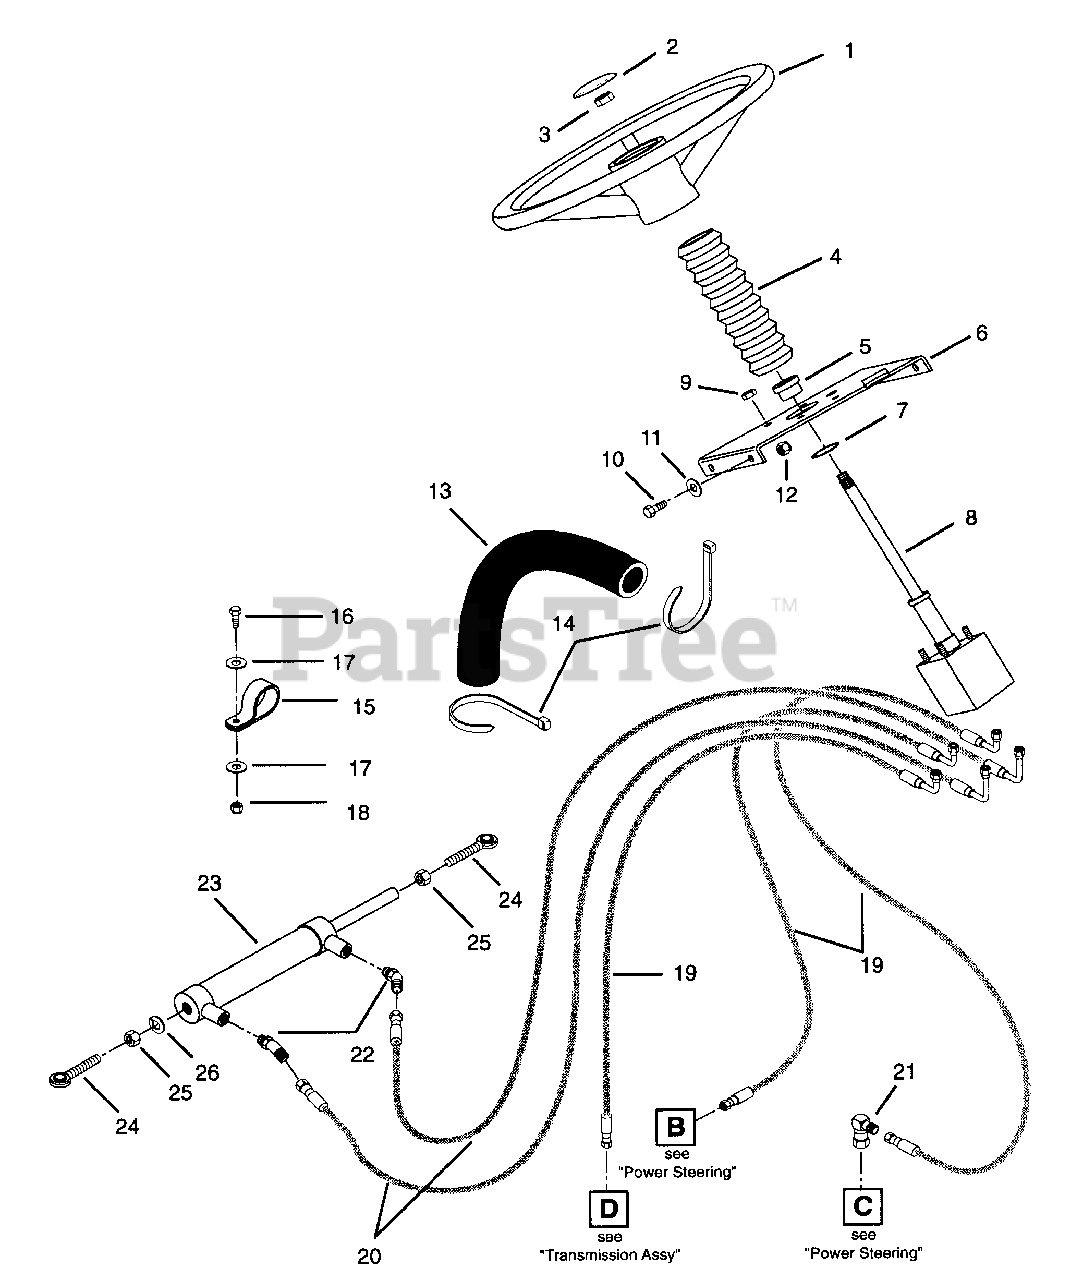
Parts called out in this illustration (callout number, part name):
1	Steering Wheel
2	Steering Wheel Cap
3	Nut-Jam .625-11
4	Steering Wheel Boot
5	Bushing-Flange .762 x 1.0 x .580 x 1.48
6	Bracket,Steering Pump
7	Ring
8	Power Steering Unit
9	Nut-Locking-Nylon .312-24 Grade 2
10	Bolt-Hex .31-18 x .75 Grade 5
11	Washer-Flat-Steel .344 x .688 x .065
12	Nut-Locking-Nylon .312-18 Grade 2
13	Sleeve 12"
14	TieWrap, Black
15	Clamp,Nylon
16	Bolt-Hex .38-16 x 1.00 Grade 5
17	Washer-Flat-Steel .406 x .812 x .065
18	Nut-Locking-Nylon .375-16 Grade 2
19	Assembly,Hydraulic Hose
20	Hydraulic Hose Assembly
21	Adapter
22	Adapter
23	Cylinder,Steering
24	Assembly,Rod End
25	Nut-Jam .50-20 Grade 2
26	Washer-Lock .50
